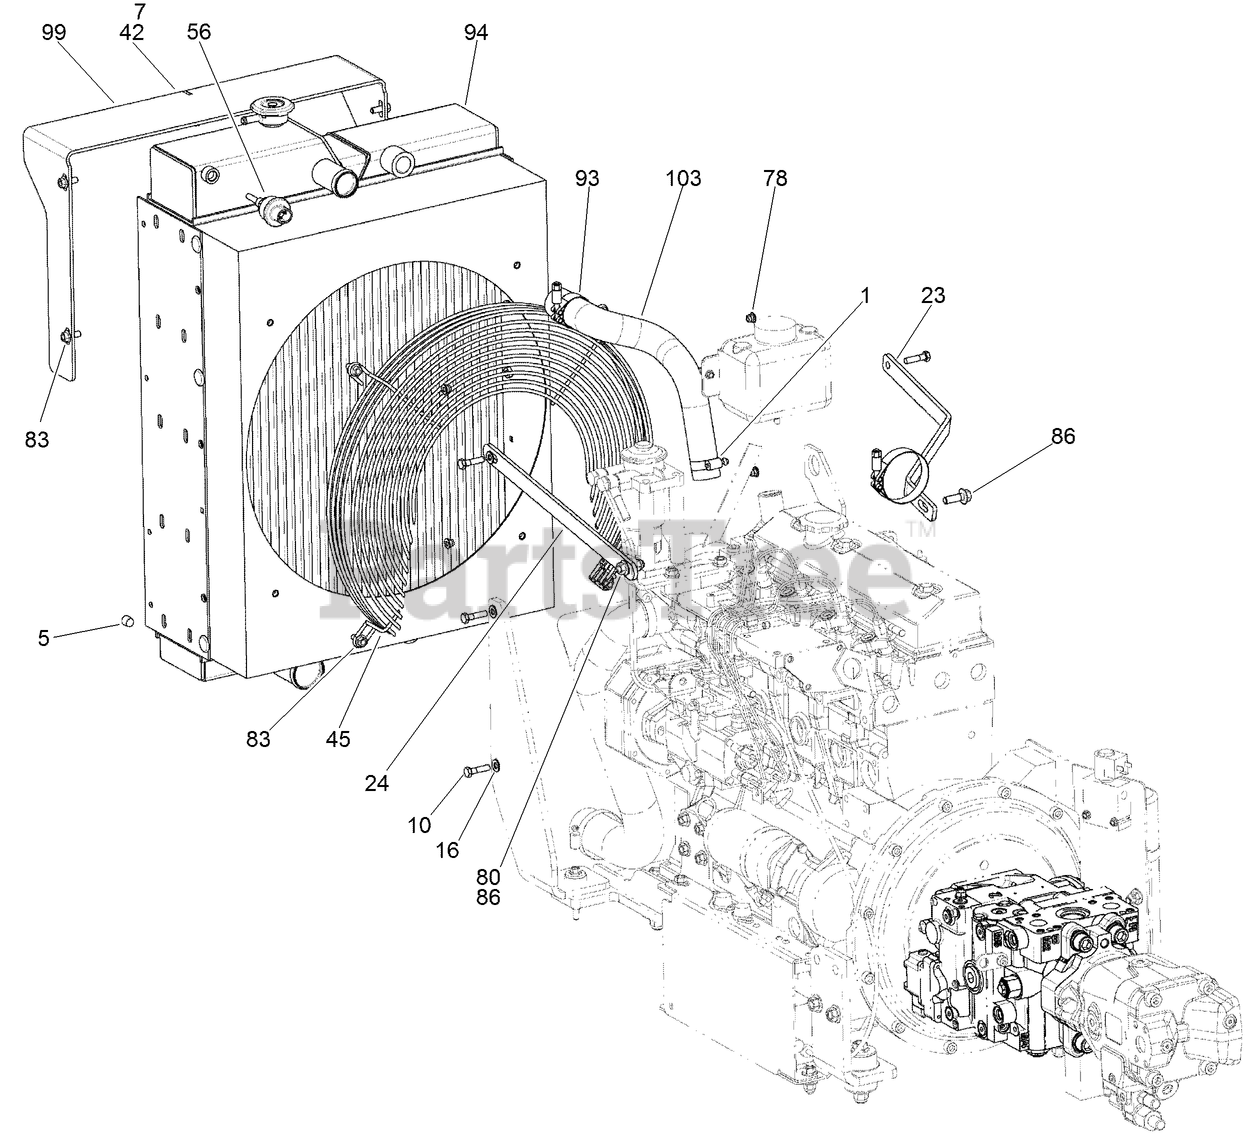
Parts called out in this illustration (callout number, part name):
1	CLAMP - Hose Type F # 24
5	PLUG - Hdls Hex Skt Pipe 1/4 ZN
7	NUT - Prev Trq 5/16 GRB ZND Direct
10	BOLT-Hex, 5/16 NC x 1-1/4 inch
16	WASHER-FLAT
23	STRAP - Radiator
24	STRAP - Radiator
42	STUD-BALL
45	GUARD-Fan
56	SENSOR - Coolant Level Switch
78	NUT, METRIC FLANGE PREVAILING - M6 Zinc
80	NUT-FLANGE, NYLOCK
83	SCREW, METRIC FLANGE w/BODY - M8 x 20
86	SCREW-HH
93	CLAMP-HOSE (T-BOLT)
94	RADIATOR - Cooling
99	ASSEMBLY - Shock Mount
103	HOSE - Upper Radiator, Molded
